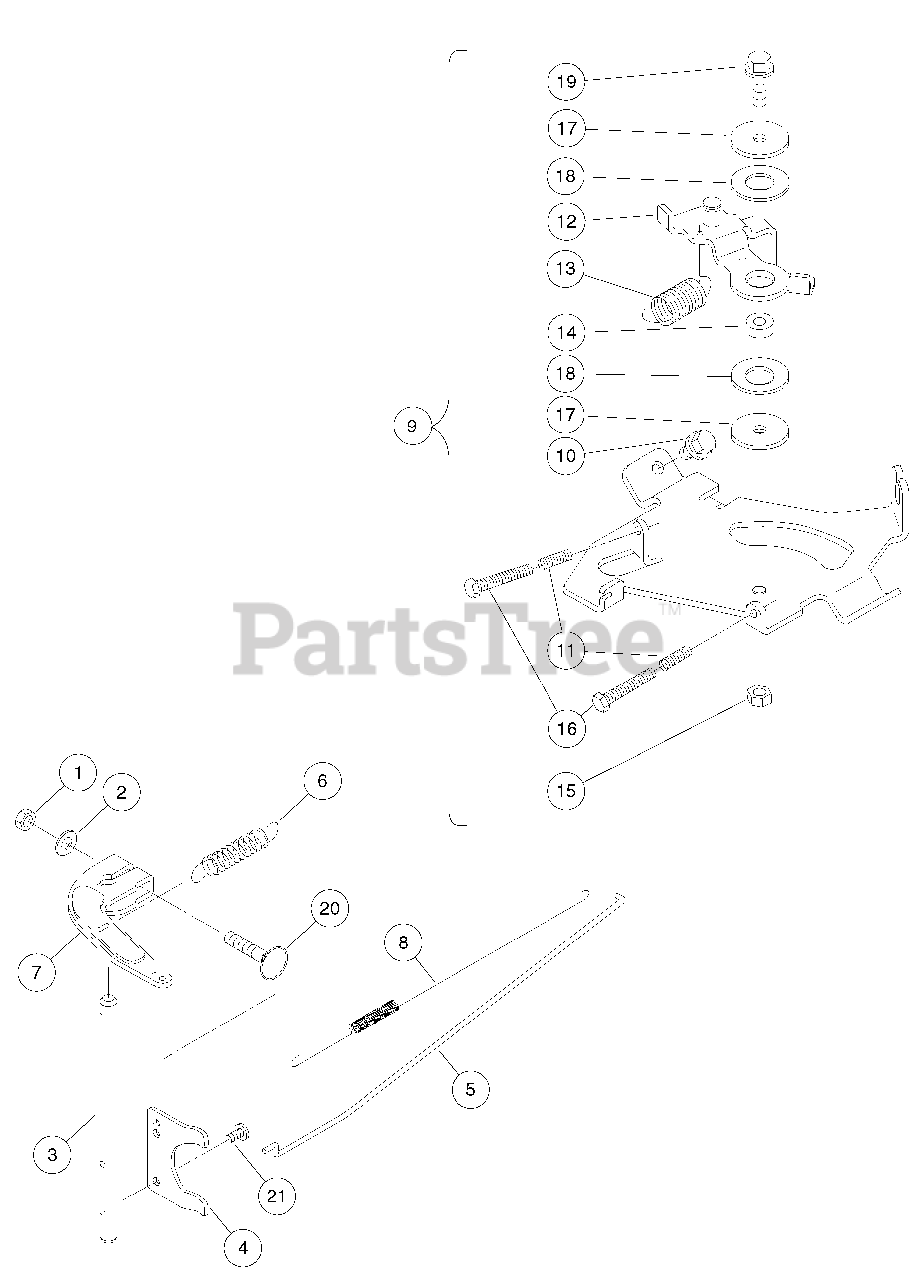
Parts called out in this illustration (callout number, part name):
1	Nut -6mm-
2	Washer, M6 Flat
3	Shaft, Governor, Fh
4	Plate, Governor, Fh
5	Link, Arm, Governor, Fh
6	Spring, Governor, Fh
7	Arm, Governor, Shaft
8	Spring, Arm, Governor, Fh
9	Panel, Control, Complete, Fh
10	Bolt, Flg, M6 X 1.0 X 12
11	Spring, Fh
12	Lever, Governor, Control, Fh
13	Spring, Governor Return, Fh
14	Collar, Governor, Fh
15	Nut, Governor, Fh
16	Bolt, Speed Control, Fh
17	Washer, Governor, Lower, Fh
18	Washer, Governor, Middle, Fh
19	Bolt, Flanged, M6 X 20, Kaw
20	Bolt, M6 X 35, Kawasaki
21	Screw, Pan, Governor, Fh
